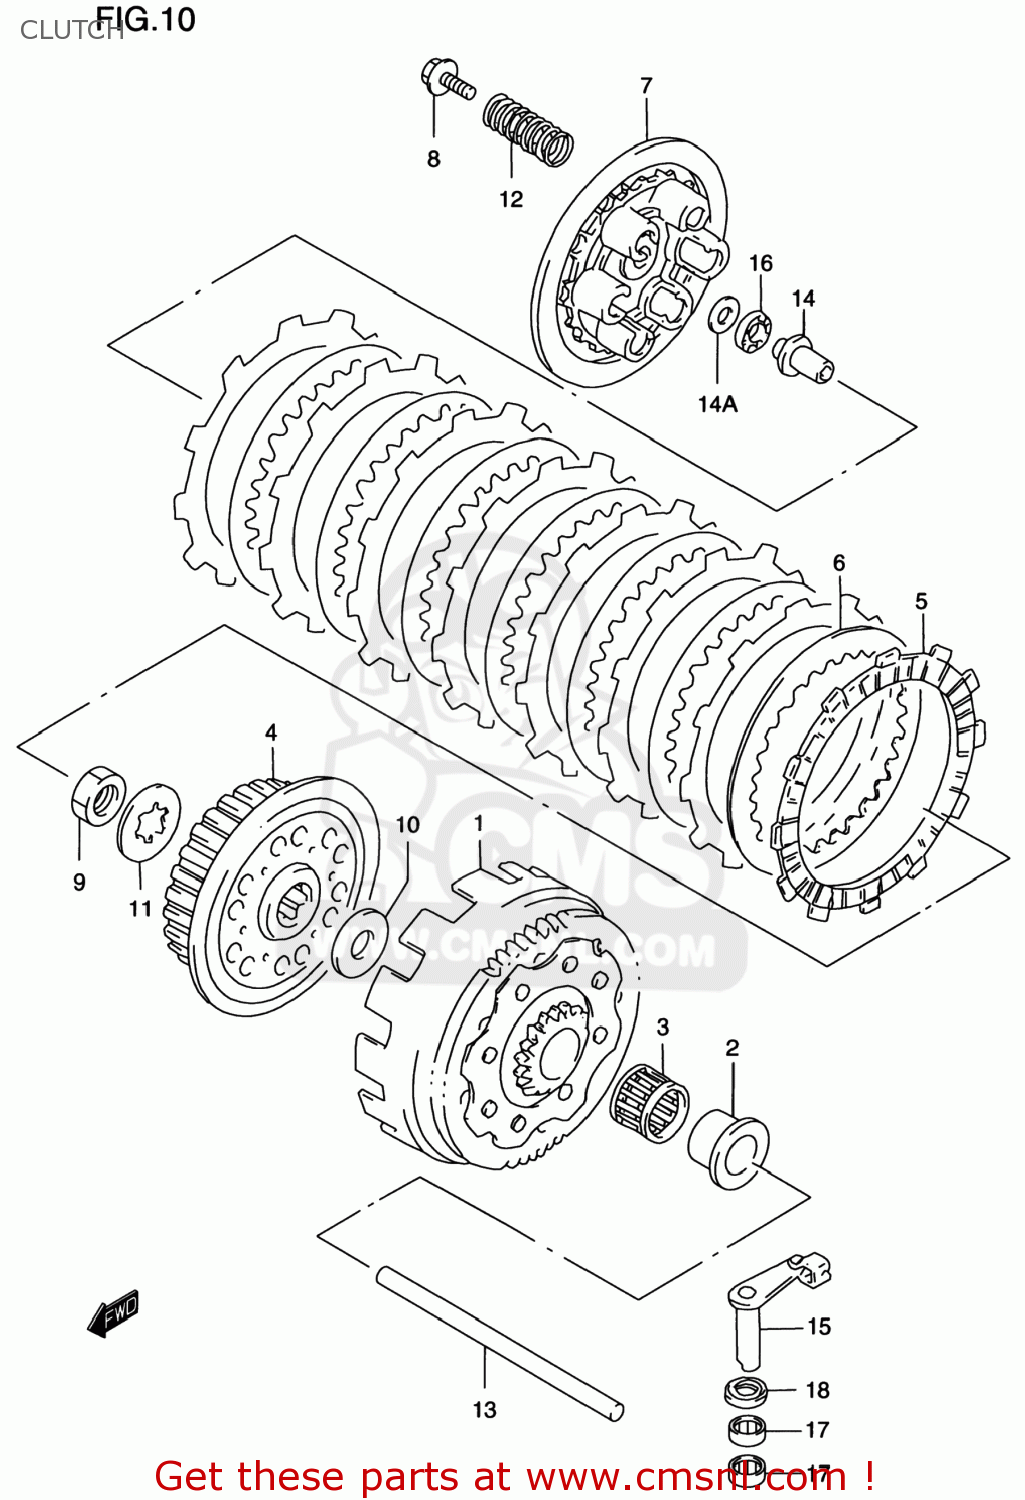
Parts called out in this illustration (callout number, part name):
1	GEAR ASSEMBLY,PRIMARY DRIVE
2	SPACER,PRIMARY DRIVEN
3	BEARING(29X34X27)
4	HUB,CLUTCH SLEEVE
5	PLATE,CLUTCH DRIVE
6	PLATE,CLUTCH DRIVEN
7	DISC,CLUTCH PRESSURE
8	BOLT(5X25)
9	NUT
10	WASHER(22X38X2)
11	WASHER,LOCK
12	SPRING
13	ROD,CLUTCH PUSH
14	PIECE,CLUTCH PUSH
14A	SHIM(10X20X0.5)
15	CAMSHAFT COMP,CLUTCH RELEASE
16	BEARING(10X22X2.8)
17	BEARING(12X16X10)
18	SEAL,OIL(12X19X5)
